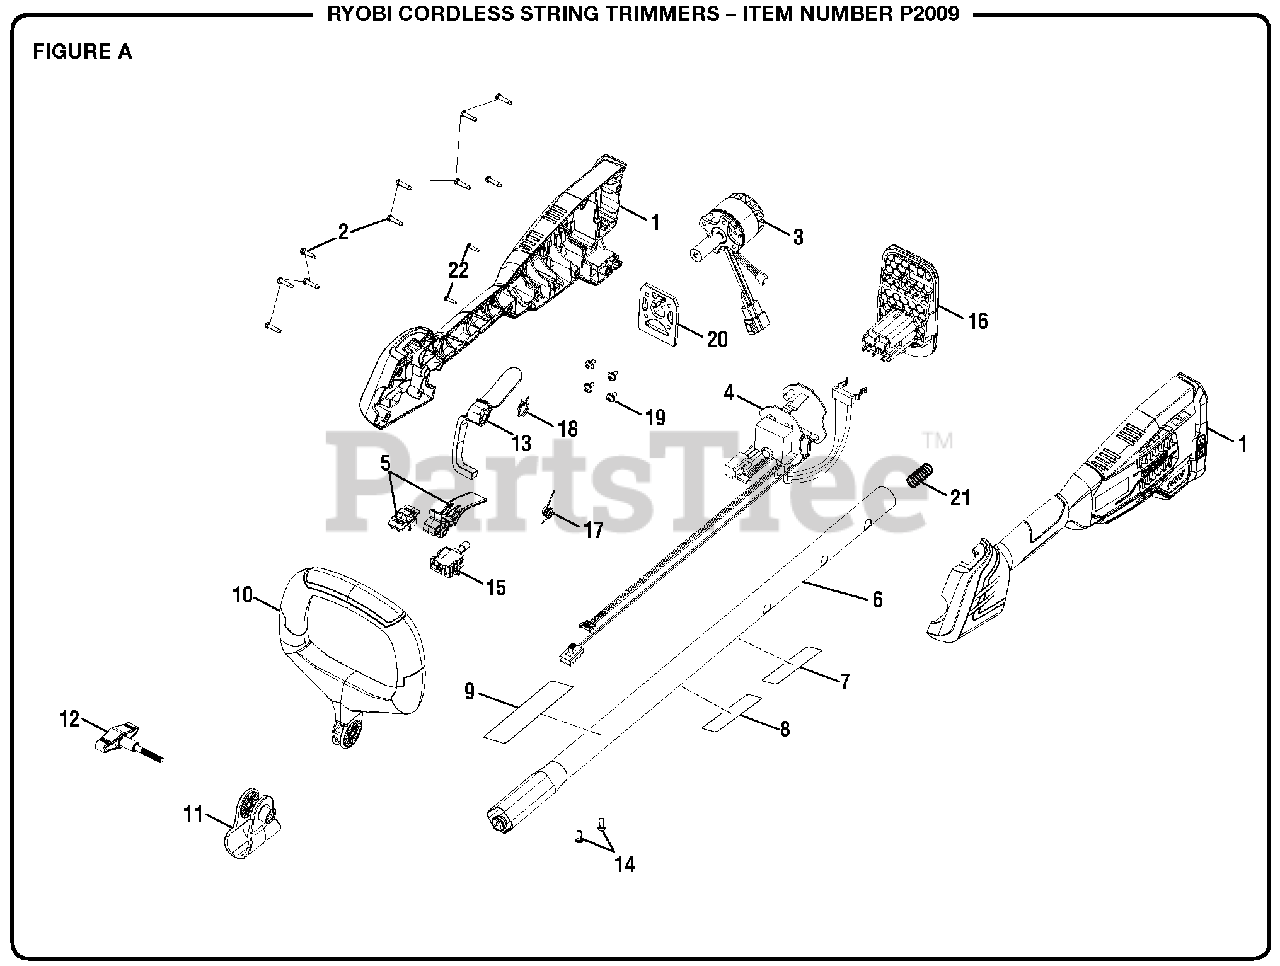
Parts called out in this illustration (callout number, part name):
1	Rear Handle Assembly
2	Screw (M4 x 16 mm)
3	Motor Assembly
4	Electric Controller and Switch Assembly
5	Trigger Assembly
6	Upper Boom Assembly
7	Warning Label (Fr/Sp)
8	Data Label
9	Warning Icon Label
10	Front Handle
11	Handle Bracket Assembly
12	Handle Knob
13	Lock-Off Trigger
14	Screw (M5 x 10 mm)
15	Variable Speed Switch
16	Battery Foot
17	Torsion Spring
18	Torsion Spring
19	Screw (M4 x 8 mm)
20	Motor Plate
21	Compression Spring
22	Screw (M3 x 8 mm, Pan Hd.)
